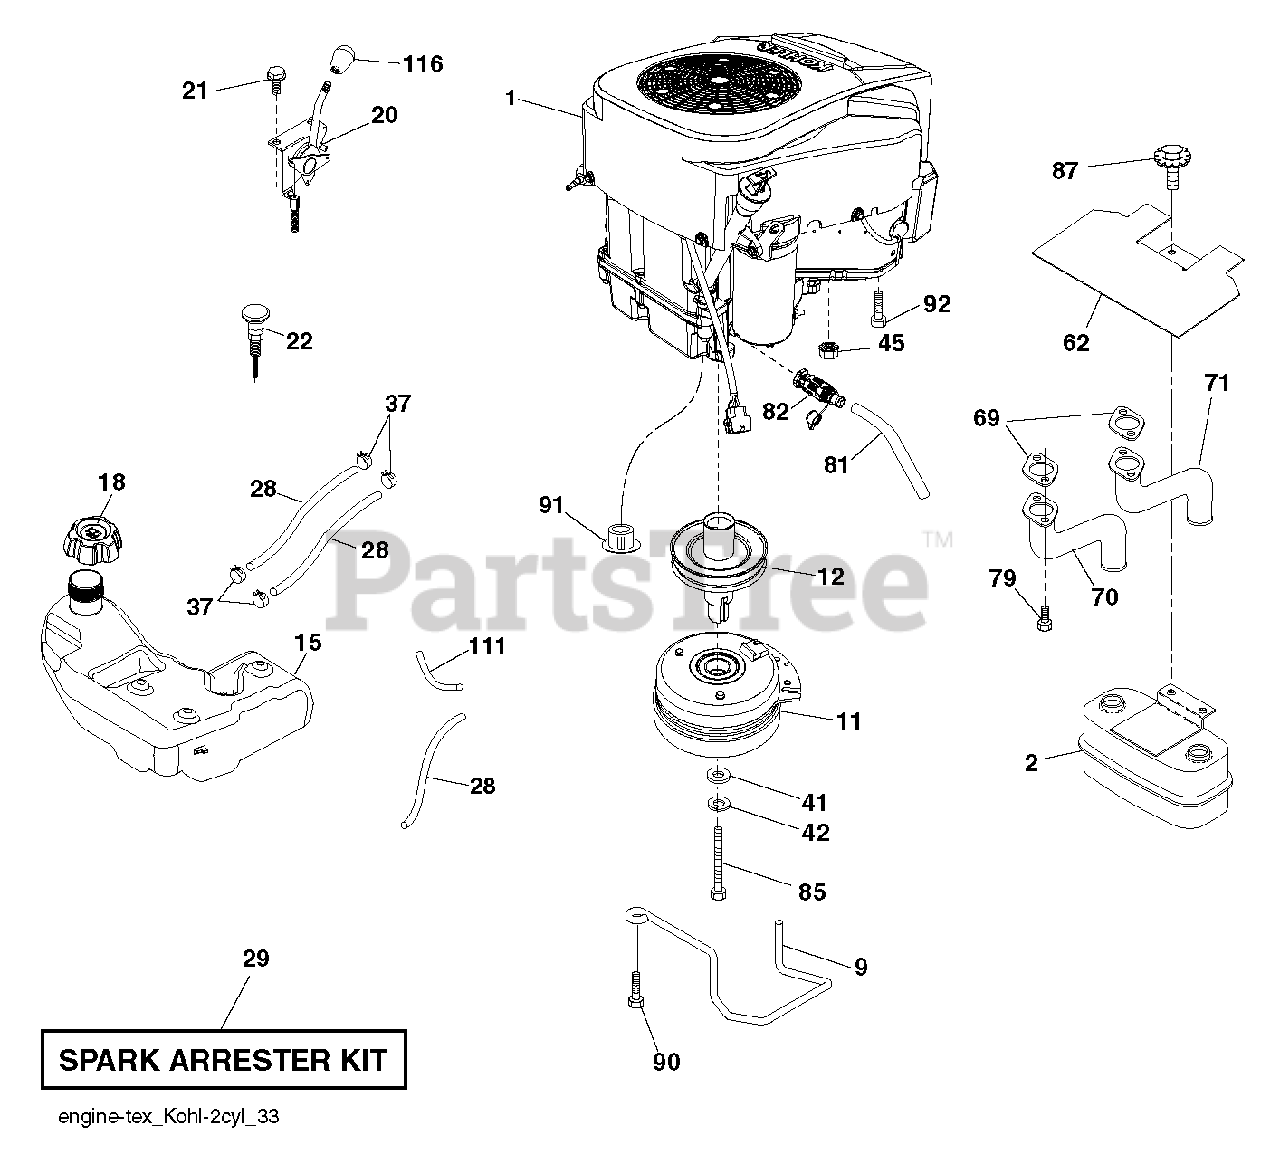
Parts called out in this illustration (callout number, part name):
2	MUFFLER.ASM.TWN.EXTNDED.DFLCTR
9	KEEPER.BELT.ENGINE.4.2
11	CLUTCH. 5.0 PD. 2.5 OFFSET
12	PULLEY.EXTENDED.SHAFT.GROUND
15	TANK.ASM.FUEL.3GA.CARB
18	CAP ASSY FUEL 3" GRAY
20	CONTROL.THROTTLE.PRO.KOHLER
21	SCREW.#10 X 0.750.BOS
22	CONTROL, CHOKE
28	LINE.FUEL.64"REAR.EMIS
29	KIT.SPARK ARRESTOR 794945 B&S
37	HOSE CLAMP
42	LOCKWASHER
45	NUT
62	SHIELD.HEAT.MUFFLER
70	TUBE.EXHAUST.LH.FR961/FR730
71	TUBE.EXHAUST.RH.FR961/FR730
79	SCREW.SOCKET HD.5/16-1
81	TUBE, DRAIN OIL ASM.
82	VALUE.OIL.DRAIN
85	BOLT.HEX.7/16-20 X 5
87	Bolt, 5/16-18 X 1-3/4
90	SCREW 3/8-16X1
91	BUSHING.1.375OD
92	SCREW 3/8-16X1
111	RP PURGE LINE
116	KNOB - SHIFT
